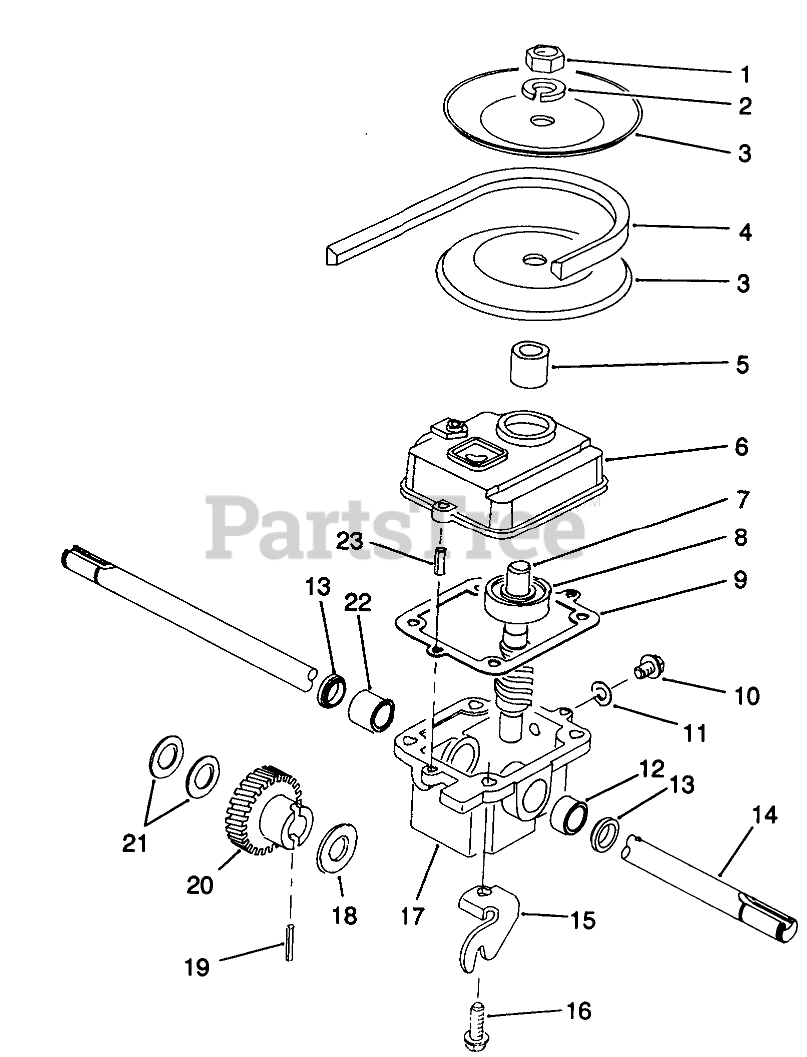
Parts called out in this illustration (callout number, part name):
1	NUT-JAM
2	WASHER-LOCK
3	PULLEY-DRIVEN HALF
4	V-BELT
5	SPACER - PULLEY
6	GEAR CASE COVER
7	SHAFT - WORM
8	BEARING
9	GASKET
10	NYLON SCREW
11	FILL PLUG GASKET
12	BUSHING
13	SEAL-OIL
14	OUTPUT SHAFT
15	TRACTION BRACKET
16	SCREW-HWHTF
17	GEAR CASE
18	THRUST WASHER
19	PIN-SPRING
20	GEAR - HELICAL
21	WASHER-PLAIN
22	BUSHING
23	3/16 X 1/2 ROLL PIN
